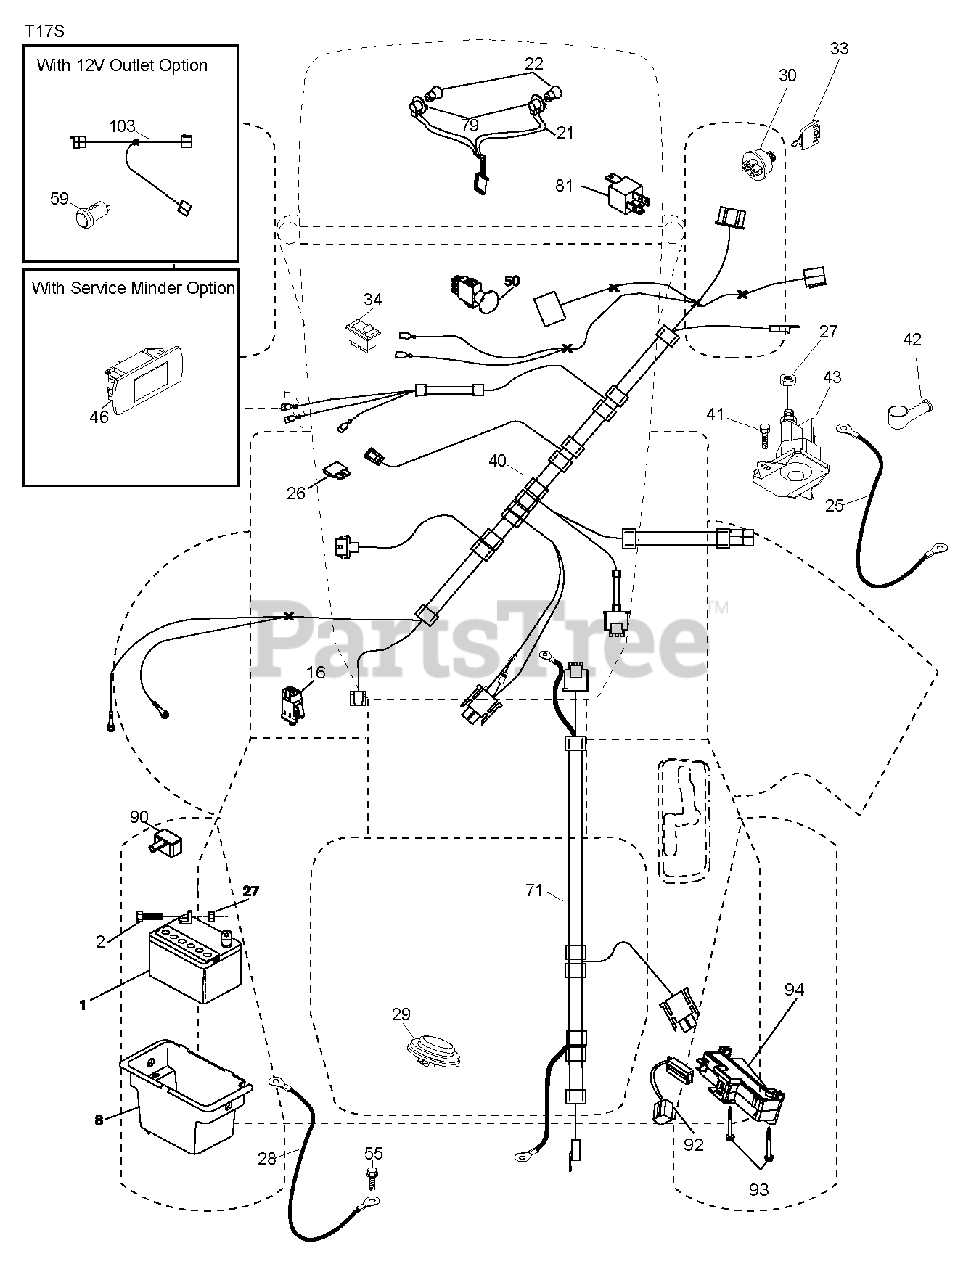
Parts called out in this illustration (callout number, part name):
1	REPL BY 532 12 38-99
8	BOX.BATTERY.MNT.REAR.L
16	SWITCH INTERLOOK PUSH-IN
21	HARNESS.LIGHT W/4152J BULBS
25	CABLE.STARTER.6GA.BL/RED.14.
27	NUT
28	CABLE.BLACK.18"REAR.BA
29	SWITCH.SEAT.DELTA.OPC.
30	SWITCH.IGN.DELTA.W.LGH.ROS
33	KEY.CHAIN.BLISTER.PACK.GEN.INT
40	HARNESS.IGN.ELE.RELAY.TEX.46"
41	SCREW
42	TERMINAL COVER
43	SOLENOID.W/BRASS.PLUNG
50	SWITCH, PTO
55	SCREW 5/16"
71	HARNESS.IGN.CHASS.TEX.REAR.BAT
79	BULB HOLDER ASM.
81	RELAY HARNESS.SEALED
90	COVER.TERMINAL.BATTERY
92	HARNESS.PIGTAIL.CONSLE
93	SCREW.PLASTITE
94	MODULE.REVERSE.ROS
